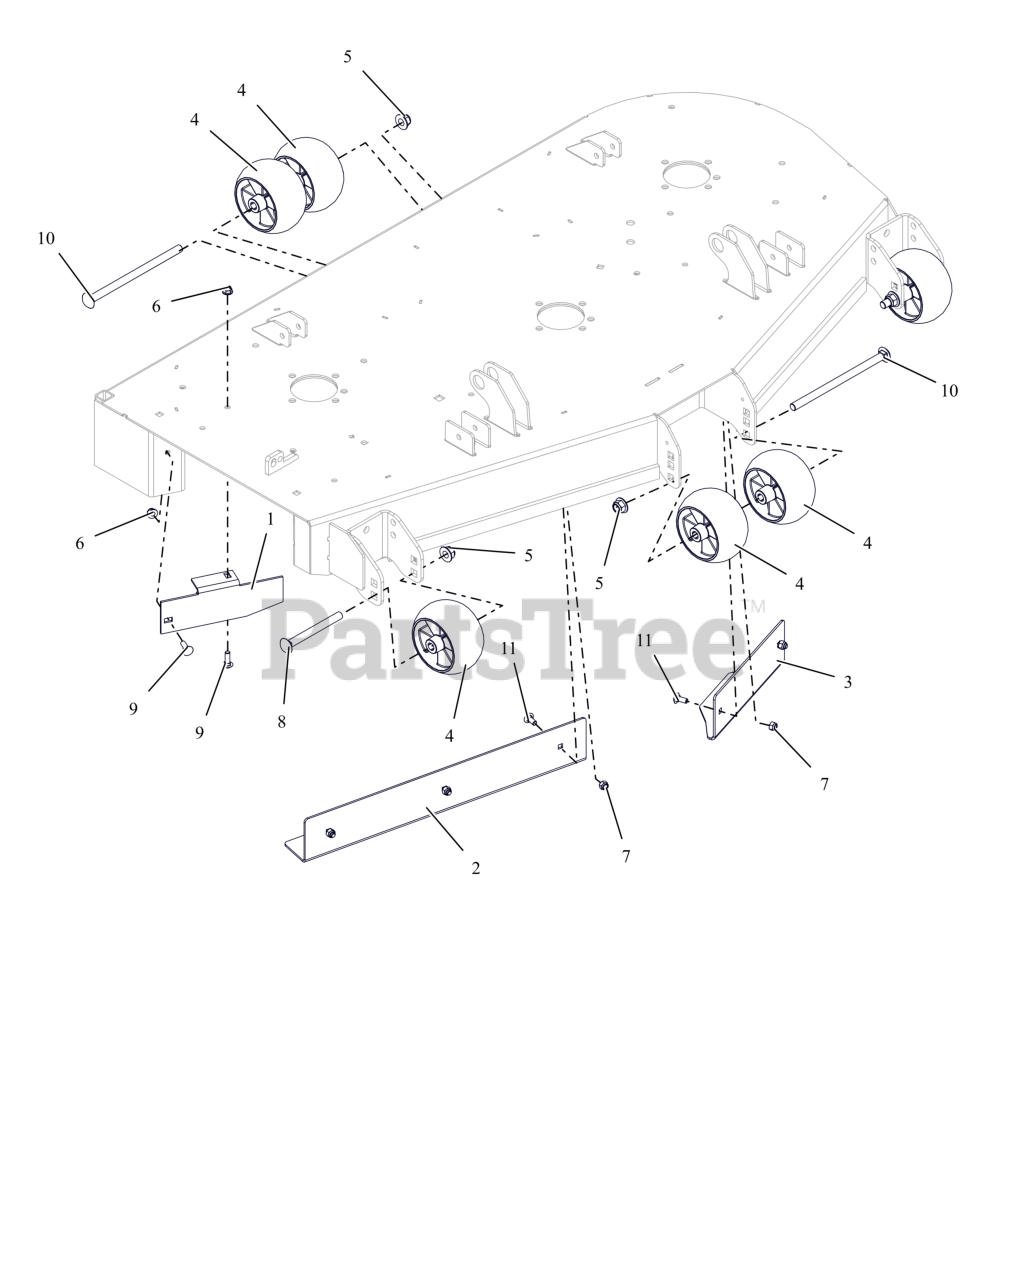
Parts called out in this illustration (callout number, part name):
1	BAFFLE, DISCHARGE, 52"
2	BAFFLE, 52" RH VACUUM (RED)
3	BAFFLE, 52" LH VACUUM (RED)
4	WHEEL, ANTI SCALP - 5X3 CTR W/RIBS
5	NUT,NYL-FLG .50-13 GF ZCC
6	NUT,NYL-FLG .31-18 GF ZCC
7	NUT,NYL .31-18 G5 ZCC
8	BLT, RHSN .50-13X5.00 G5 ZCC
9	BLT,RHSN .31-18X1.00 G5 ZCC
10	BTL,RHSN .500-13 X 8.5S G5 ZCC
11	BLT,RHSN .31-18X.75 G5 ZCC
